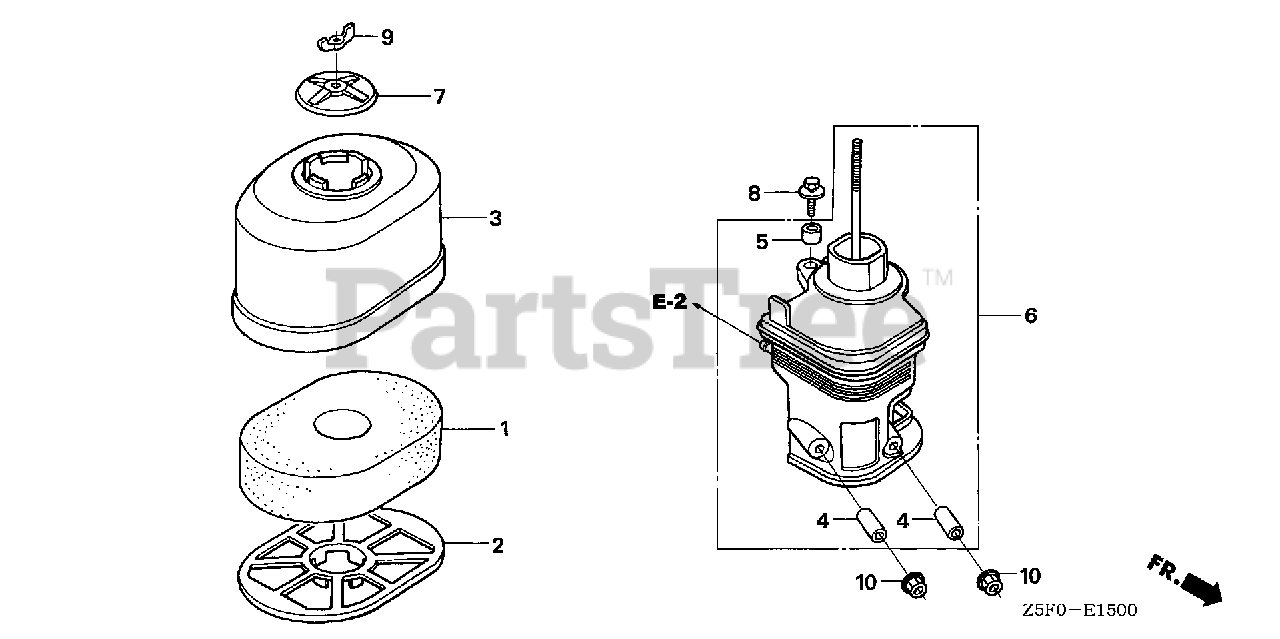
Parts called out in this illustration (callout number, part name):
1	ELEMENT, AIR CLEANER (SEMI-DRY)
2	GRID, AIR CLEANER
3	COVER, AIR CLEANER (SEMI-DRY)
4	COLLAR, AIR CLEANER
5	COLLAR B, AIR CLEANER
6	ELBOW, AIR CLEANER
6	ELBOW COMP, AIR/C
7	CAP, AIR CLEANER
8	BOLT-WASHER (6X22)
9	NUT, TOOL BOX SETTING
10	NUT, FLANGE (6MM)
